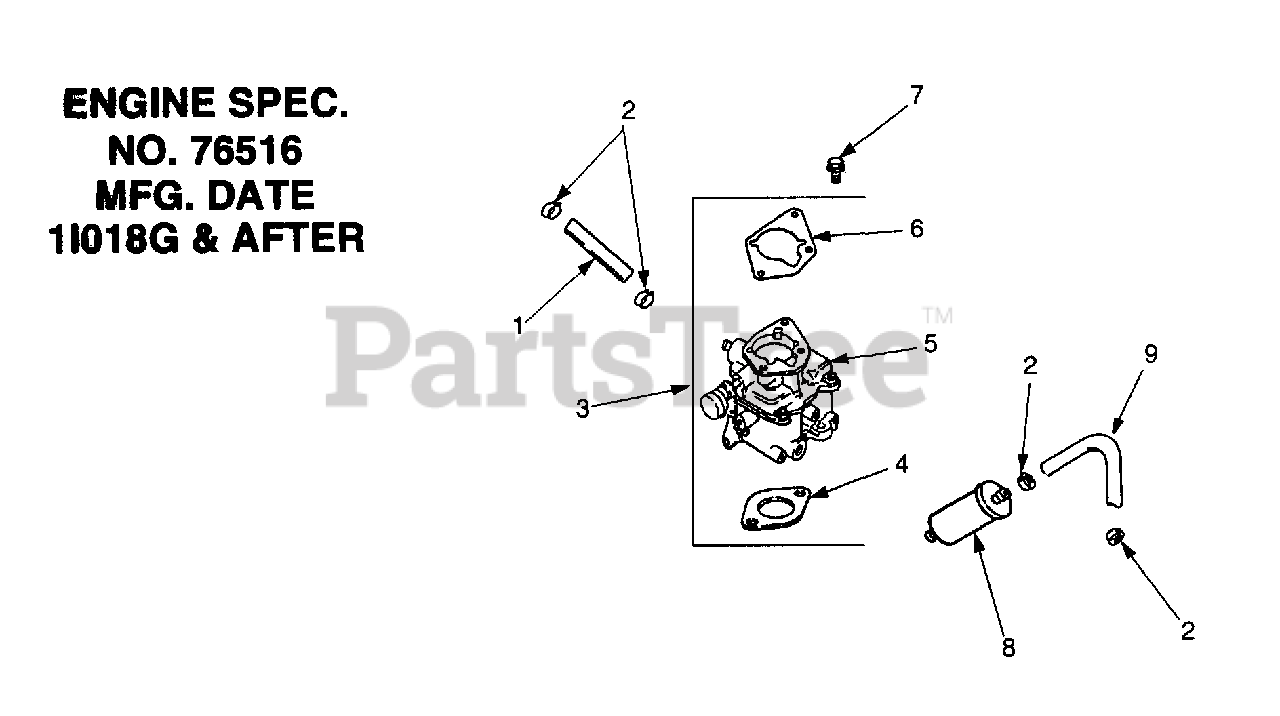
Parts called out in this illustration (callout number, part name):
1	Line, Fuel 10"
2	Clamp, Hose
3	Kit, Carburetor w/Gasket
4	Gasket, Carburetor
5	Carburetor Assembly
6	Gasket, Air Cleaner Base
7	Screw, Hex Flange
8	Filter, Fuel
9	Line, Fuel 11"
